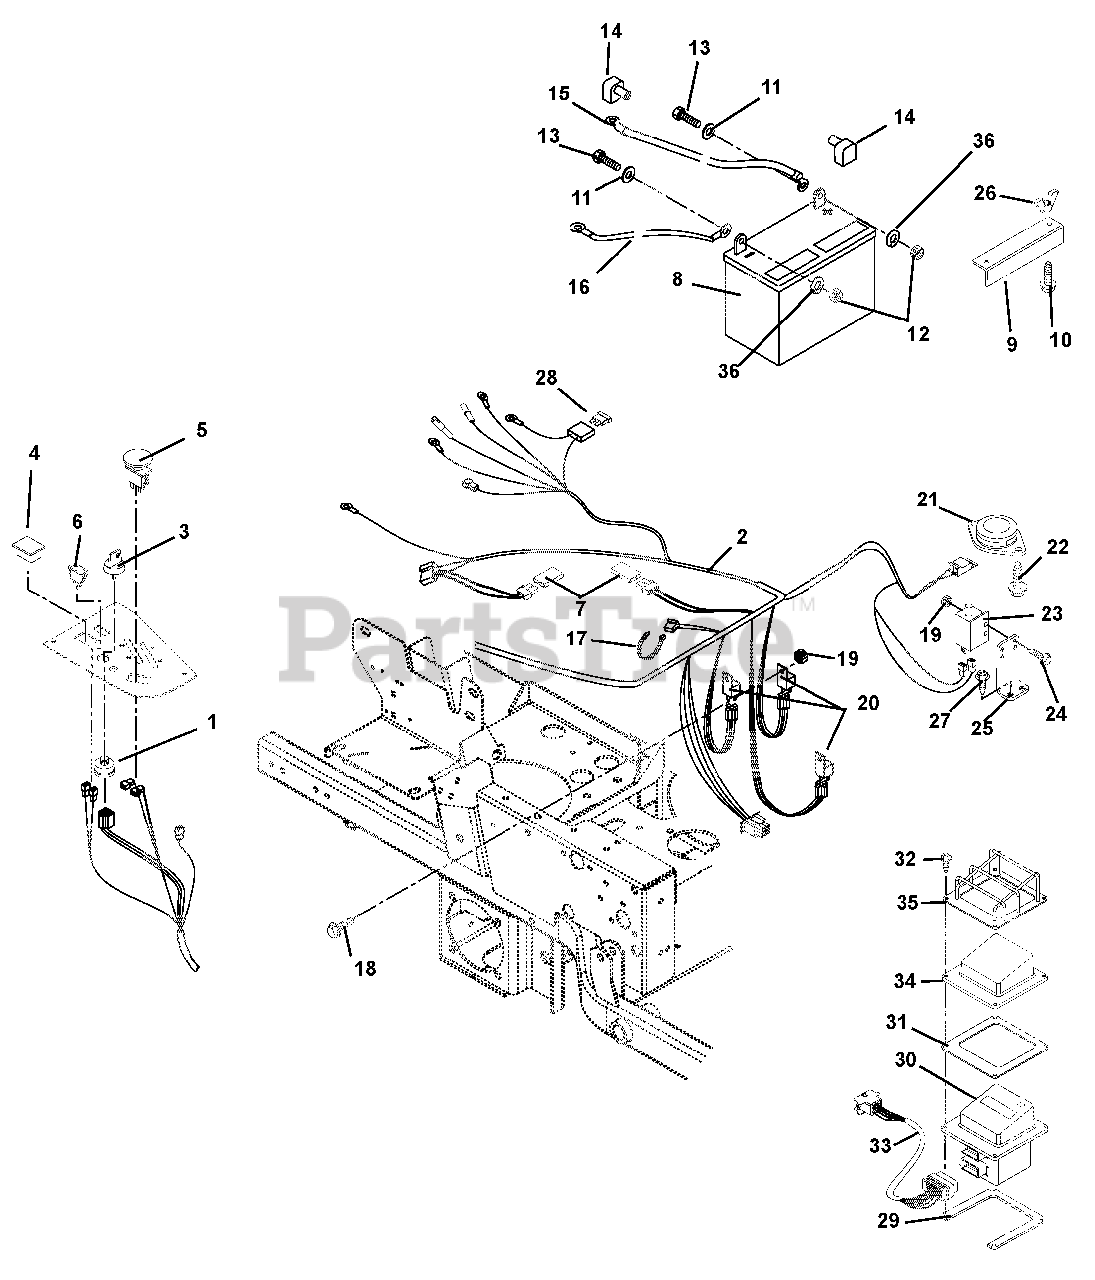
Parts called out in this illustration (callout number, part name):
1	SWITCH, IGNITION
2	HARNESS - IZ VERTICAL A/C
3	KEY, W/ SHIELD
4	PLUG, HOUR METER
5	SWITCH, CLUTCH
6	LIGHT,INDICATOR
7	DIODE, CONNECTOR SHELL
8	BATTERY, 300 CCA 10U1L
9	HOLD DOWN
10	BLT-RDHDSQNK .25-20X7.50 GR2YZ
11	@WSHR-FL-STL.281X.62X.065 YWZC
12	@NUT-HEX .25-20 YWZC
13	@BLT-HEX .25-20X.75 GR5 YWZC
14	INSULATOR
15	CABLE-POSITIVE BATTERY 26.00"
16	CABLE-NEGATIVE BATTERY 24.00"
17	CABLE TIE LG 5-1/2
18	@SCR-MCH 10-24X.50 HWH YWZC
19	@NUT-LK-NYL 10-24 W/INSRT YWZC
20	RELAY,SEALED W/DIODE
21	SWITCH- SEAT
22	@SCR-TAP 12-24X.50 HWH TR YWZC
23	SWITCH- DOUBLE POLE N.O./N.O.
24	@SCR-MCH 10-24X.75 HWH YWZC
25	BRAKE SWITCH MOUNT - BLACK
26	NUT-LK WING .250-20 YWZC
27	@SCR-TAP .25-20X.50 HWH TR YWZ
28	FUSE, 30 AMP.
29	SPACER, ENCLOSURE MTG. (BTM)
30	EYE Q ENHANCED
31	GASKET-EYE Q
32	SCR-MCH 10-24X1.0 SL PAN BLACK
33	HARNESS - EYE-Q
34	GUARD, ELEMENT
35	WMT, EYE-Q GUARD (BLACK)
36	@WSHR-LK .25X.062 REG YWZC
